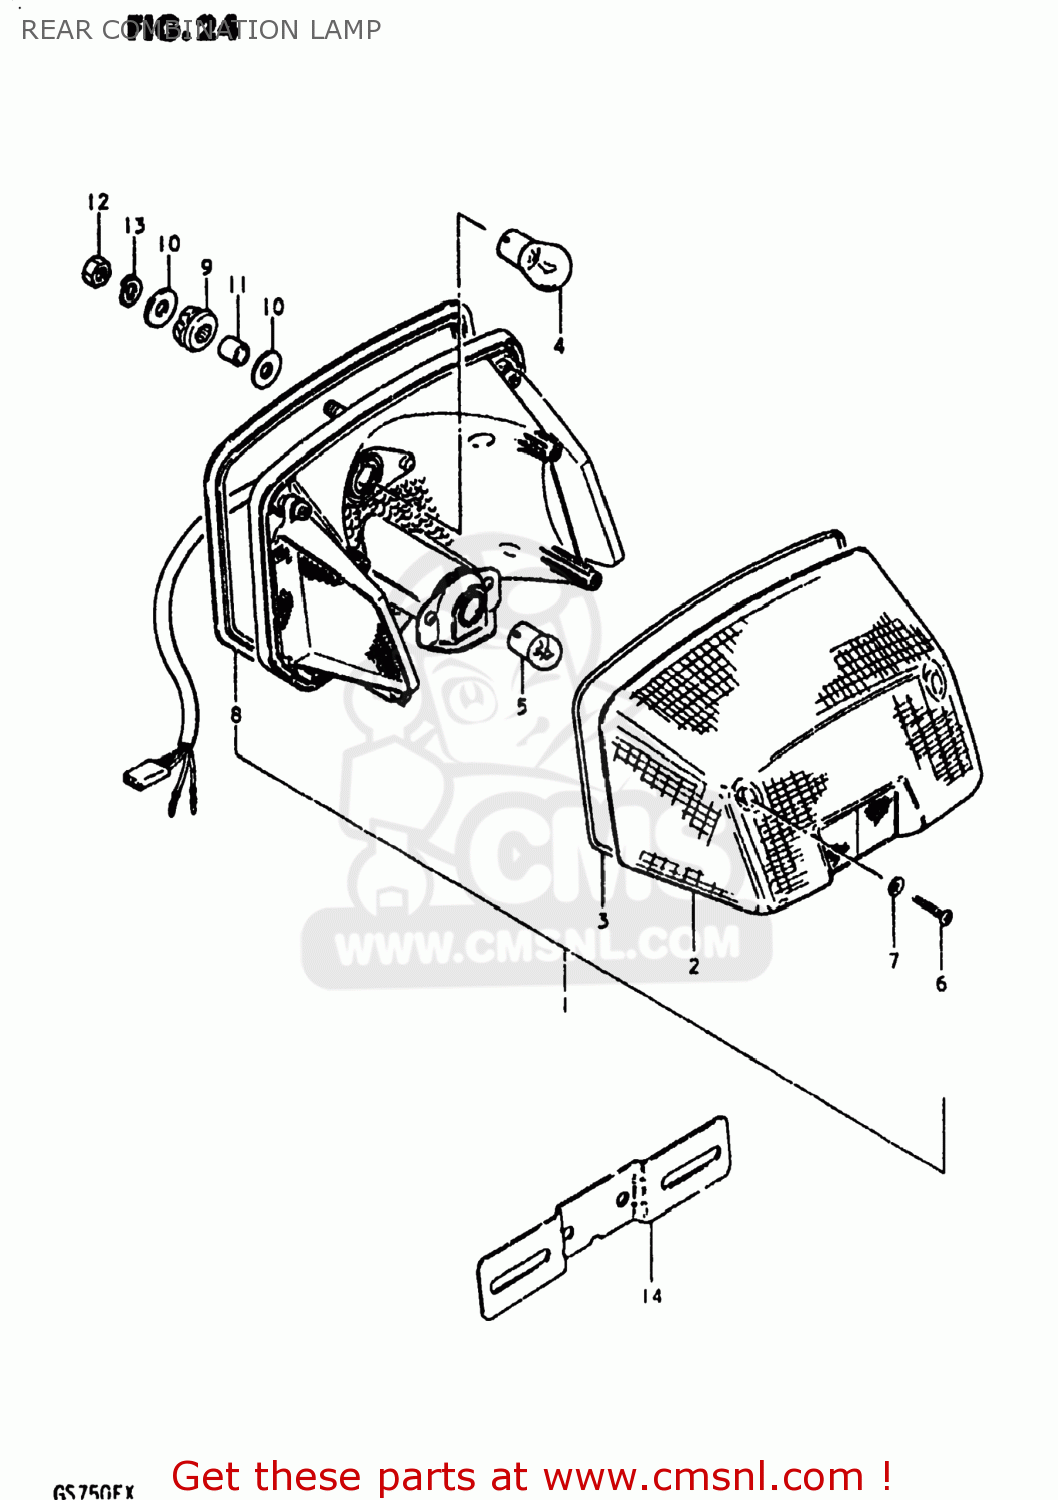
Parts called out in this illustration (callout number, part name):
1	LAMP ASSEMBLY,REAR COMBINATION
2	LENS
3	GASKET (NAS)
4	BULB(12V23W)
5	BULB
6	SCREW
7	GASKET (NAS)
8	GASKET,REAR COMBINATION LAMP
9	CUSHION
10	WASHER
11	SPACER (6.8X10X11.5)
12	NUT
13	LOCK WASHER
14	PLATE,REAR LICENSE
